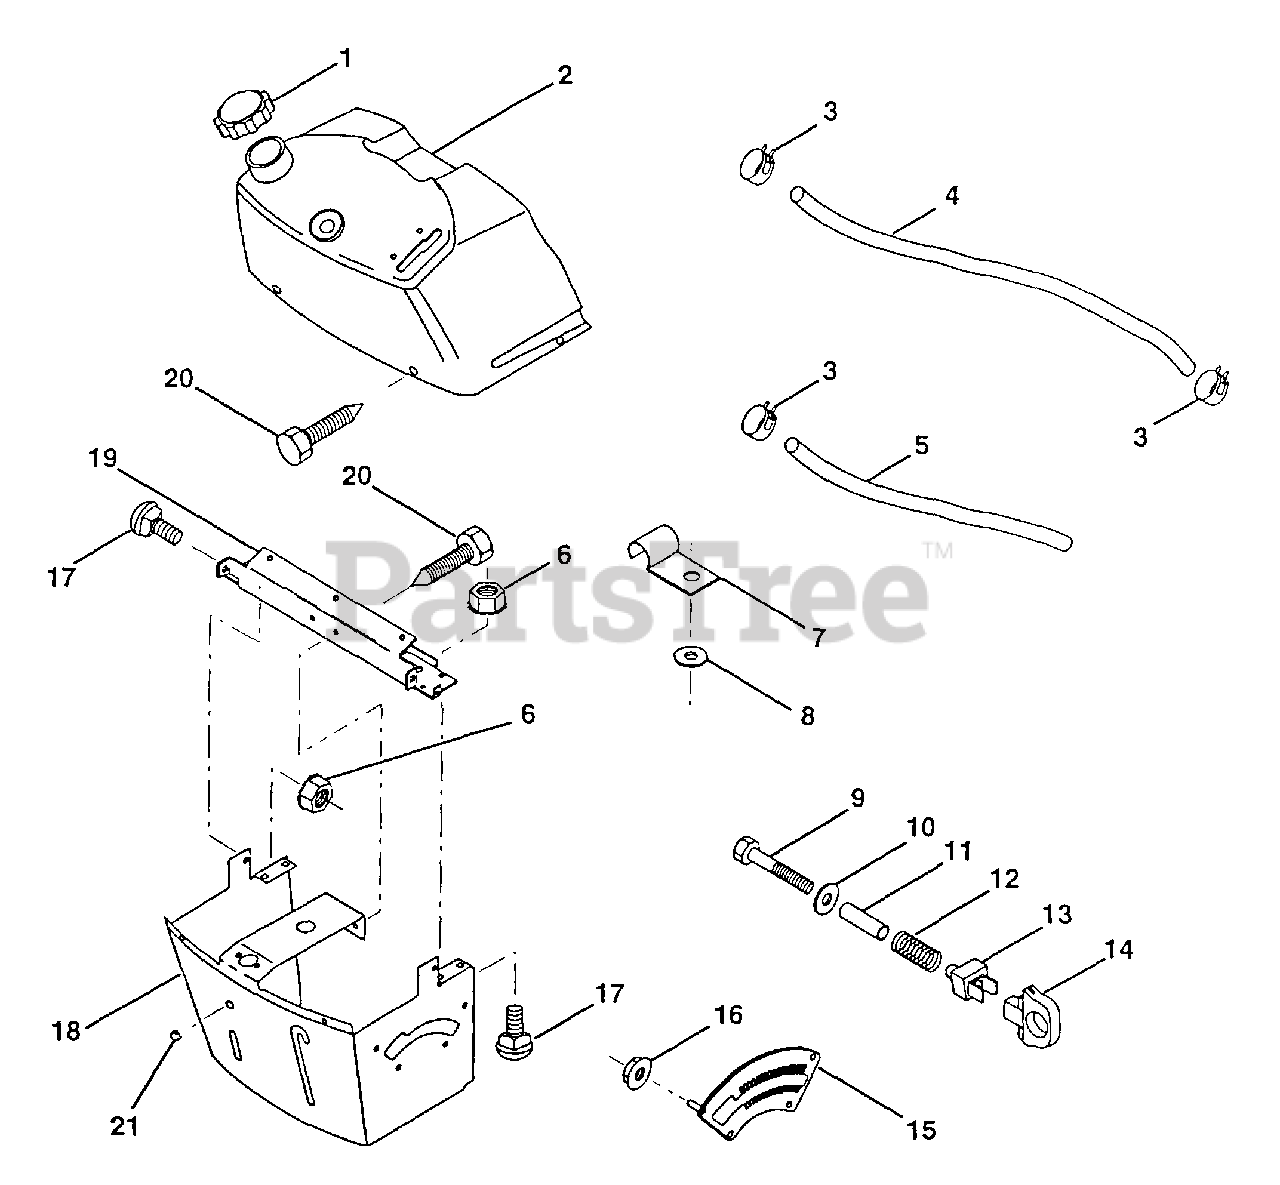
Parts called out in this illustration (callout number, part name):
1	Cap, Fuel
2	Assembly, Dash & Fuel Tank
3	Clamp, Hose
4	Line, Fuel (AYP part number)
5	Line, Fuel
6	Nut, Hex, Keps 1/4-20
7	Clip, Fuel Line
8	Washer 9/32 x 3/4 x 16 Ga.
9	Bolt, Hex, Fin 1/4-20 x 1-3/4 (AYP part number)
10	Washer 11/32 x 11/16 x 16 Ga.
11	Spacer, Split
12	Spring
13	Clip, Height Adjustment
14	Knob, Height Stop
15	Adjustment, Quadrant Height
16	Nut, Self-Threading 3/16-18
17	Bolt, Carriage 1/4-20 x 1/2 Gr. 5
18	Support Assembly, Dash
19	Brace, Cross
20	Screw, Self-Tapping 1/4-20 x 1/2
21	Plug Dome Black
